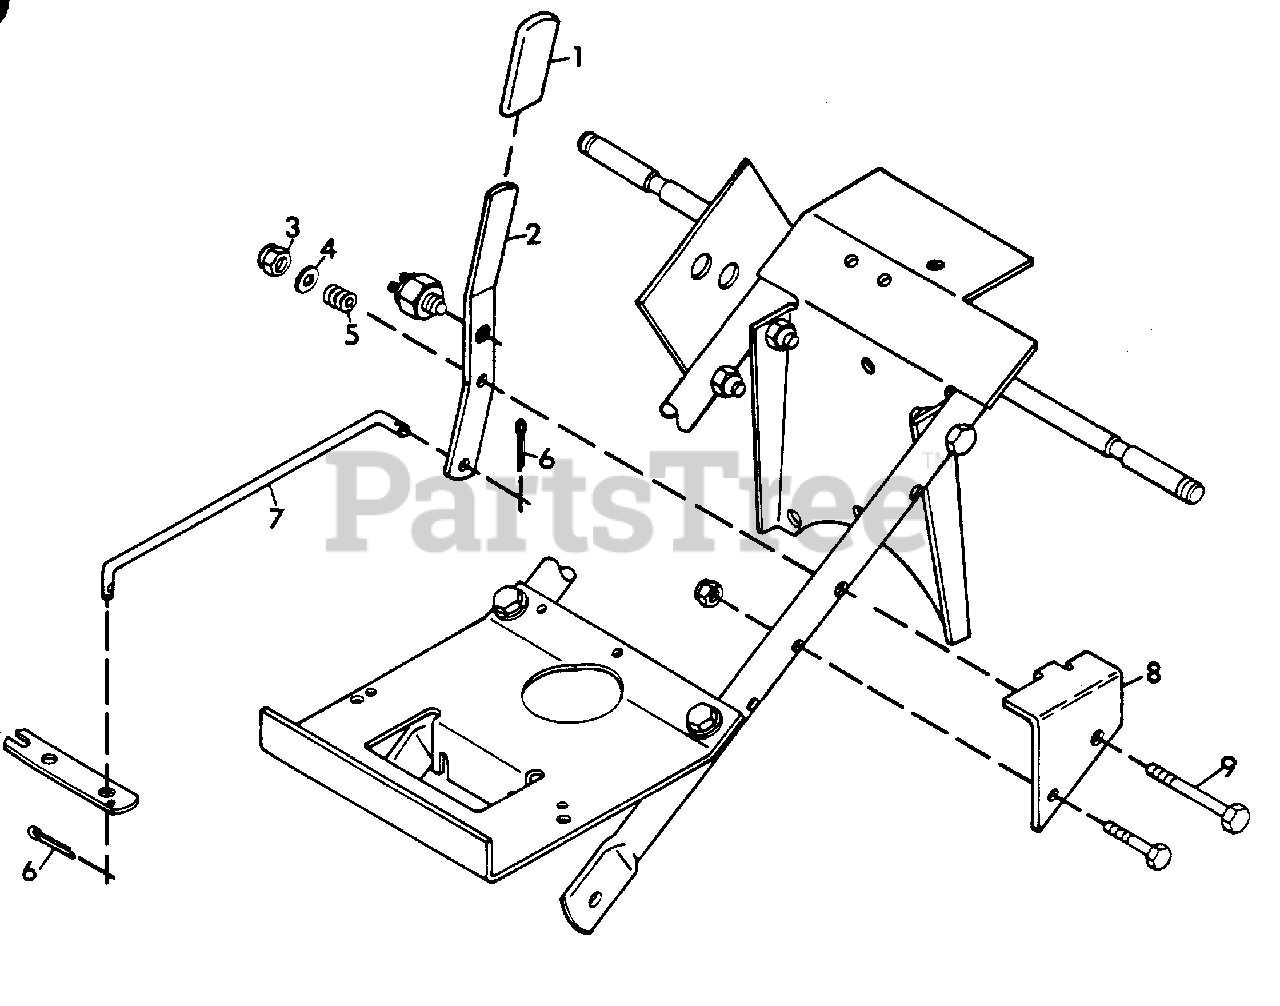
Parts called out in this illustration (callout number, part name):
1	GRIP, HANDLE
2	LEVER, PTO
3	NUT, LOCK 3/8-16
4	WASHER, FLAT .406X.812X.065
5	SPRING, COMP. 1X.78
6	PIN, COTTER .09X1.00
7	ROD, PTO
8	BRACKET, PTO
9	BOLT, HEX 3/8-16X3.25
